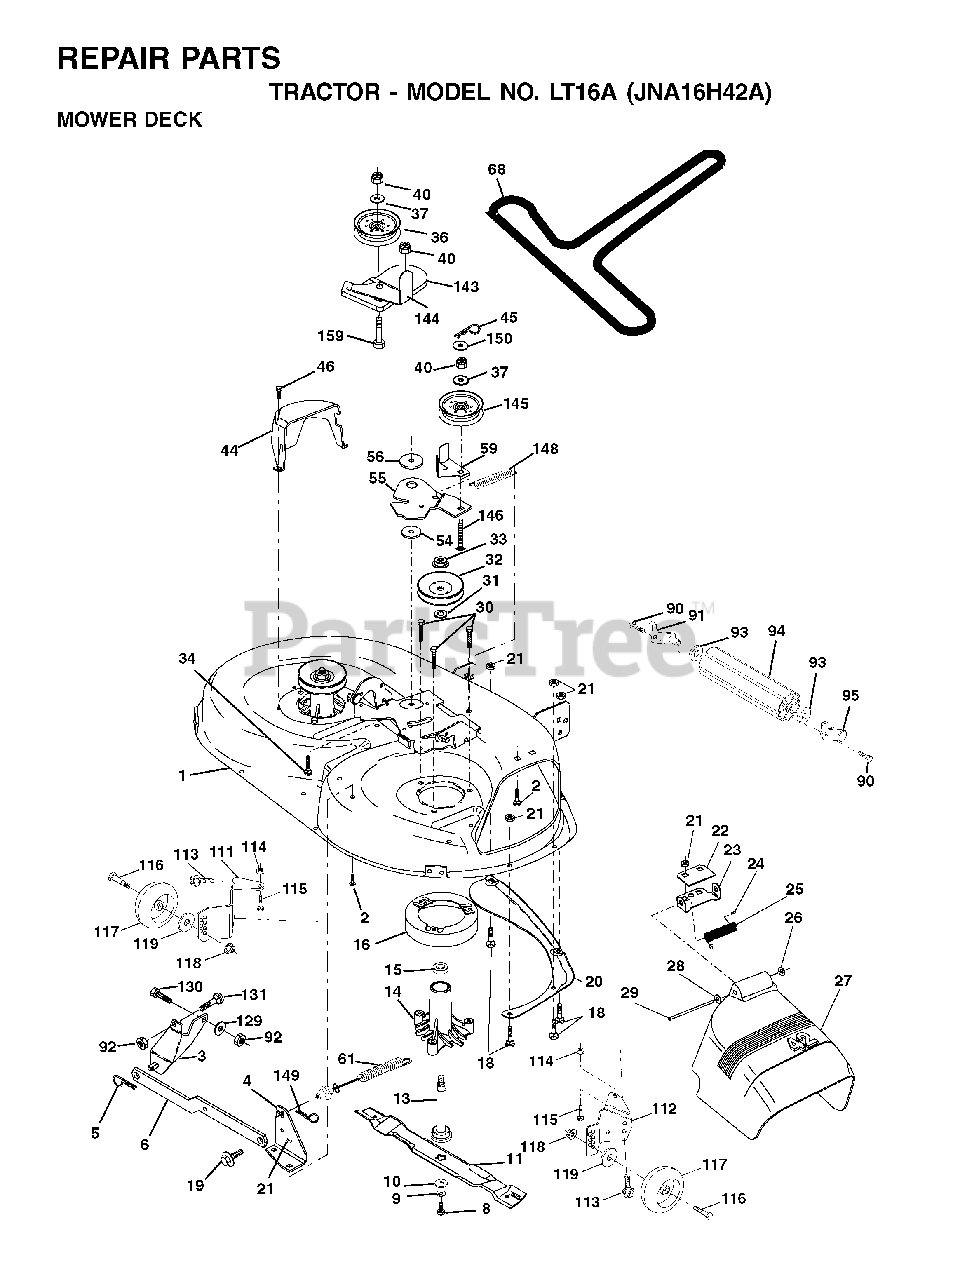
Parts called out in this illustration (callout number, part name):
1	42" DECK KIT
2	BOLT
3	BRKT ASM SWAY BAR
4	BRACKET SWAY BAR 42" DECK
5	RETAINER-SPRNG RB
6	REAR SUSP ARM
8	BLADE BOLT
9	LOCKWASHER
10	WASHER.BLADE
11	BLADE 42"
13	SHAFT ASM VENT
14	HSG MANDREL
16	STRIPPER, MWR ROUND
18	BOLT
19	BOLT SHD 5/16-18
20	BAFFLE.VORTEX
21	LOCKNUT
22	STIFFENER BRACKET
23	DEFLECTOR BRACKET
24	CAP-SLEEVE LT
25	SPRING TORSION
26	NUT PUSH M
27	SHIELD DEFLECTOR
28	WASHER
29	ROD.HINGE
30	SCREW THDROL ROLLING WASHER HD
31	WASHER
32	PULLEY/MANDREL
33	NUT, FLG TOPLOCK 9/16"
34	BOLT
36	FLAT IDLER PULLEY
40	LOCKNUT
44	GUARD MANDREL LH BLACK
45	RETAINER M
46	SCREW.1/4-20X5/8
54	HARDENED WASHER
55	ARM IDLER 42" MOWER LT/YT
56	SPACER.RETAINER.MOWER
59	GUARD, BELT
61	SPRING EXT ELEC CLUTCH
68	V-BELT PRIMARY 42"
90	SCREW 3/8-16X3/4
91	BRACKET ASM, ROLLER (L)
92	NUT
94	NOSE ROLLER
95	BRACKET ASM, ROLLER (R)
113	SCREW 5/16"
114	NUT
115	BOLT
116	PEDAL COVER T
117	WHEEL.GAUGE.STANDARD
118	LOCKNUT
119	WASHER
129	WASHER
131	BOLT D
144	KEEPER.BELT.42".CLUTCH.CABLE
145	PULLEY
146	BOLT, CARRIAGE IDLER BLACK
148	IDLER RETURN SPRING
149	SPRING.RETAINER.YELLOW.ZINC
150	WASHER PM
159	BOLT
532134149	BLADE.42".MULCH
